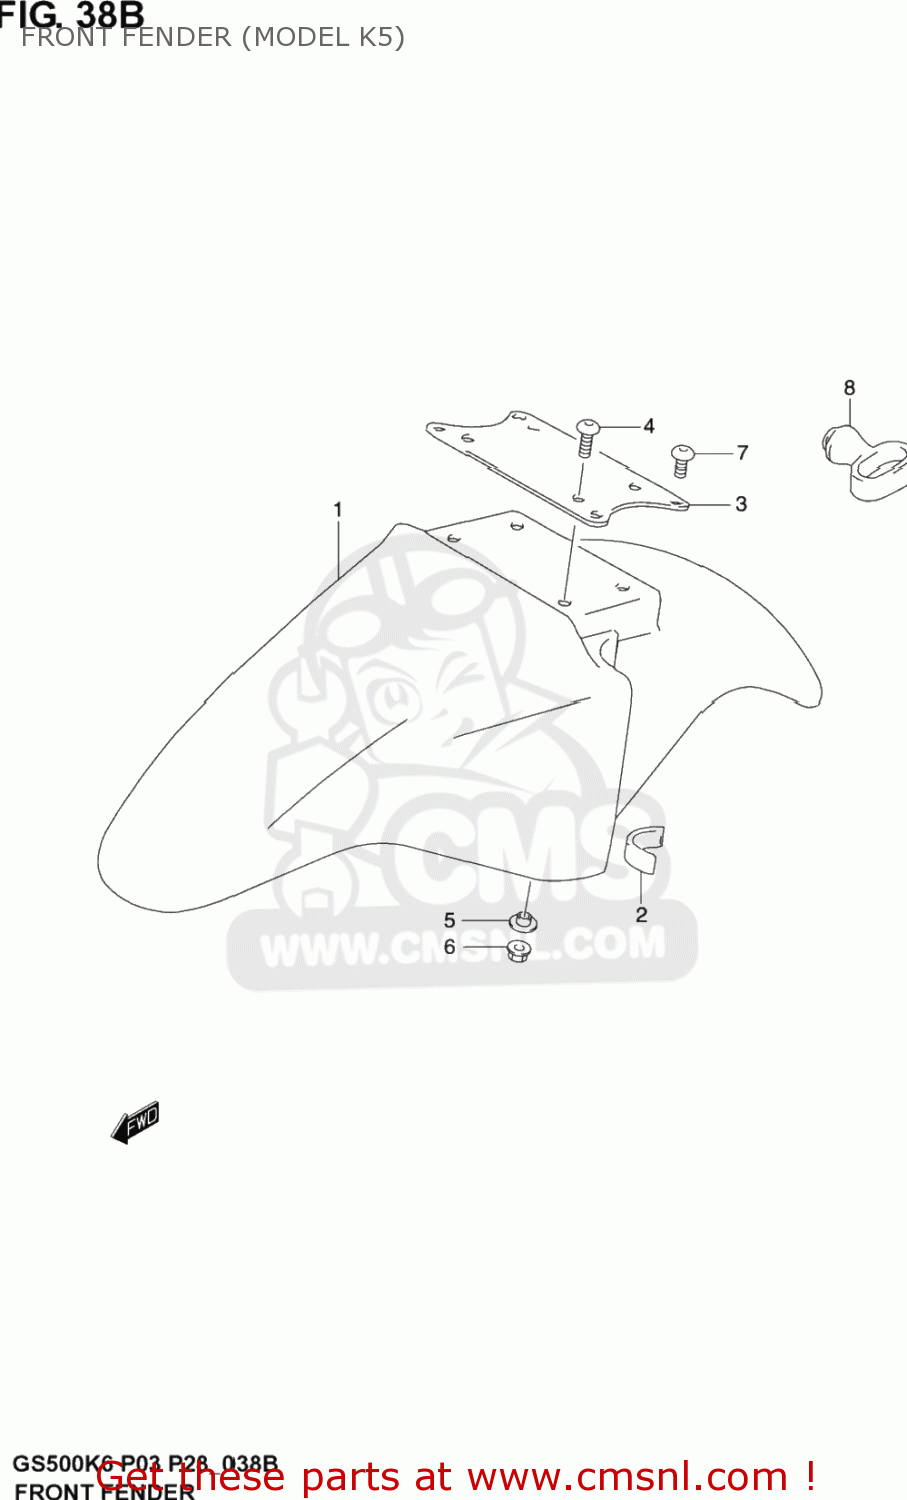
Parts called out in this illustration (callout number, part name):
1	FENDER, FRONT
2	CUSHION
3	BRACE, FRONT FENDER (BLACK)
4	SCREW(5X18)
5	WASHER
6	NUT
7	SCREW(6X12)
8	GUIDE,CABLE
